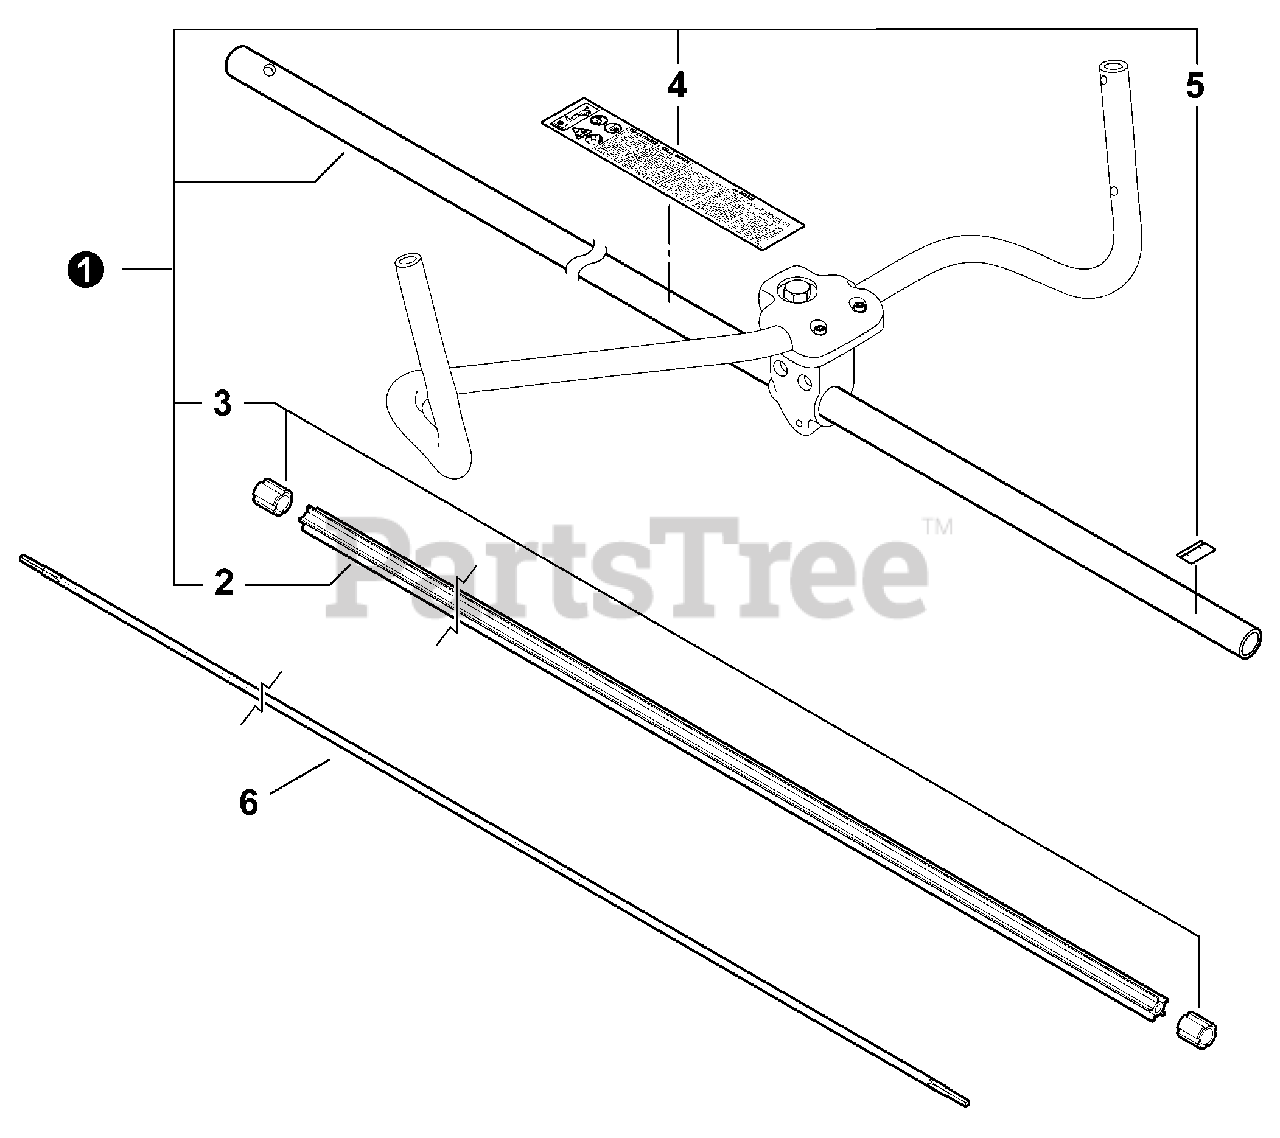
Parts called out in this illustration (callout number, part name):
1	PIPE, MAIN
2	LINER, FLEXIBLE 21.6×1420
4	LABEL, CAUTION
5	LABEL - ALIGNMENT
6	DRIVESHAFT - FLEXIBLE
